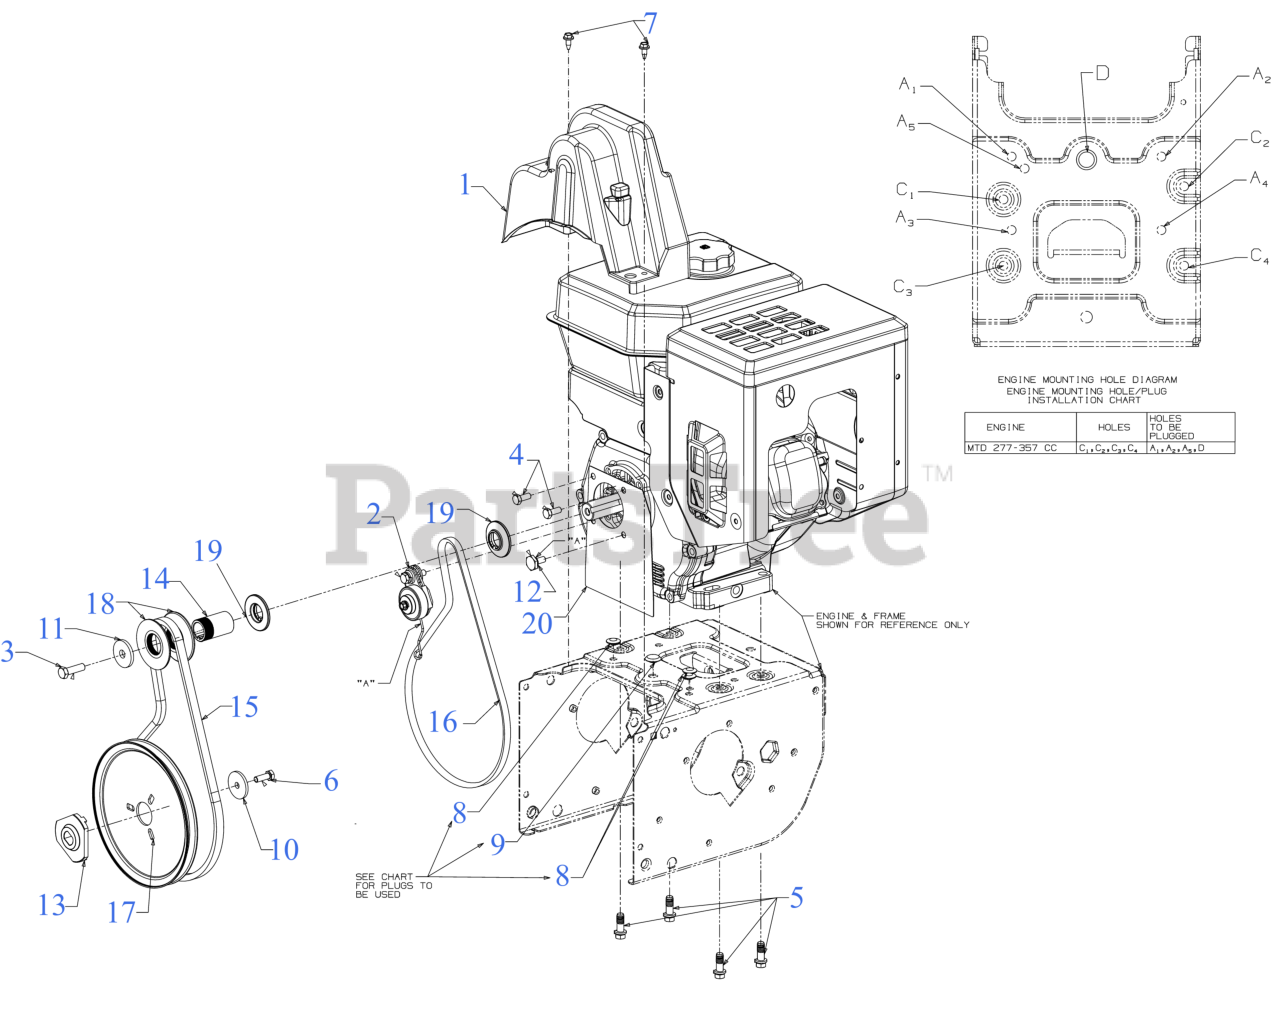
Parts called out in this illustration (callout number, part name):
1	BELT COVER SERVICE KIT (631-05322)
2	IDLER ASSEMBLY
3	SCREW 3/8-24X1.25
4	SCREW 5/16-24 x .750 GR5
5	SCREW 3/8-16 x 1
6	SCREW 5/16-24 x .875 GR5
7	SCREW 1/4-20X.625
8	PLUG-3/8 DIA ID x 3/32
9	PLUG-1/2 ID x 3/32
10	FLAT WASHER
11	FLAT WASHER .45 x 1.5 x .172 HT
12	SHOULDER SCREW
13	ADAPTER PULLEY .75 DIA W/DD
14	PULLEY SPACER
15	BELT-.500 x 37.00
16	V-BELT 3/8 x 35.68"
17	AUGER PULLEY
18	HALF PULLEY 4L V x 2.6 OD
19	HALF PULLEY-3/8 V x 1.7160
20	ENGINE PLATE (FRONT COVER)
